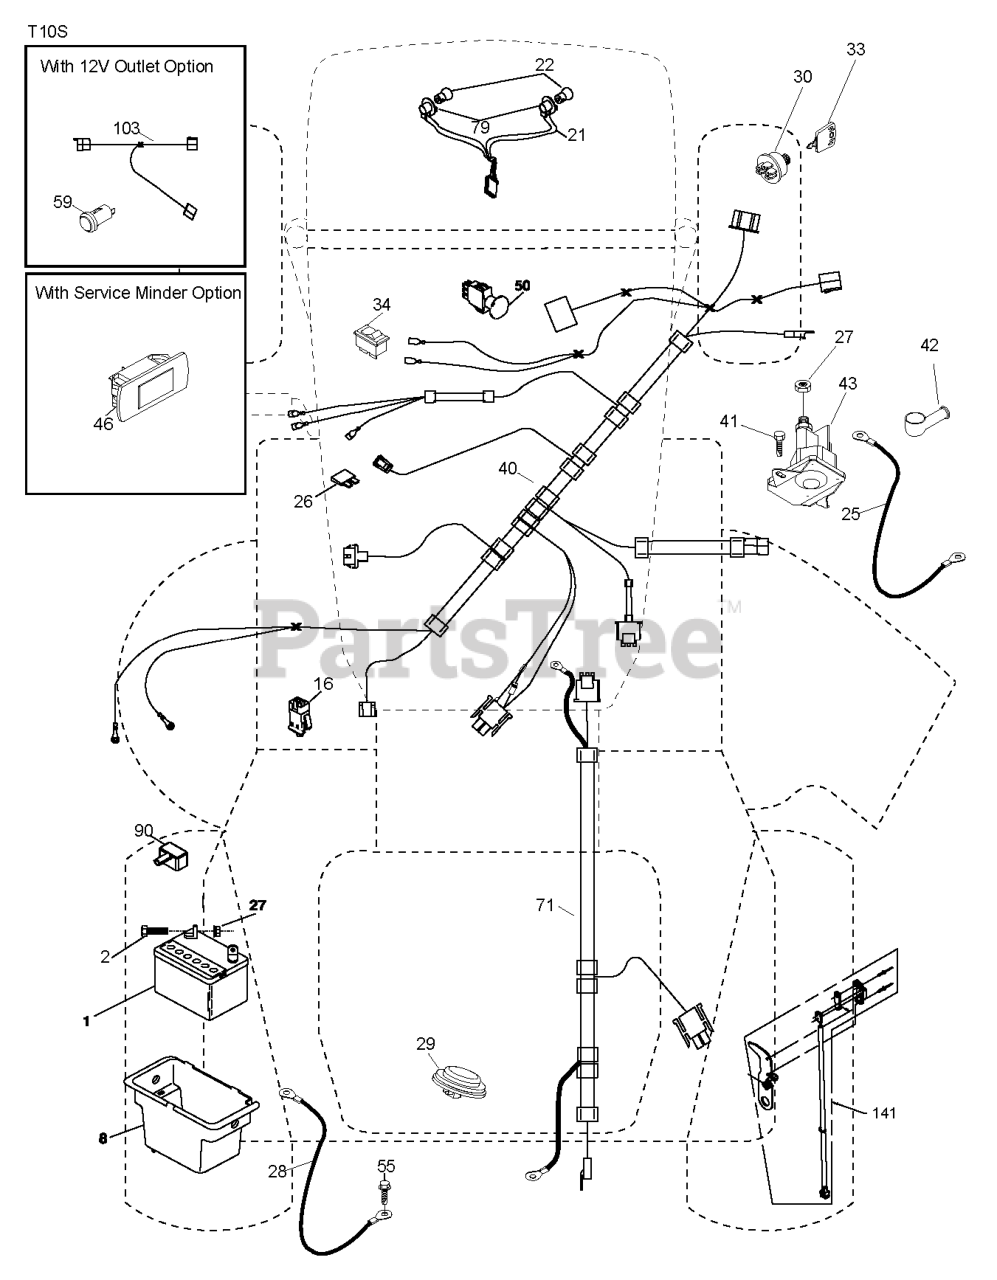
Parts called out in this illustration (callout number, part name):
1	REPL BY 532 12 38-99
2	BOLT.HEX.1/4.X.3/4.DICHROMATE
8	BOX.BATTERY.MNT.REAR.L
16	SWITCH INTERLOOK PUSH-IN
21	HARNESS.LIGHT W/4152J BULBS
25	CABLE.STARTER.6GA.BL/RED.14.
26	FUSE 20AMP
27	NUT
28	CABLE.BLACK.18"REAR.BA
29	SWITCH.SEAT.DELTA.OPC.
30	SWITCH.IGN.DELTA.W.LGH.ROS
33	KEY.CHAIN.BLISTER.PACK.GEN.INT
40	HARNESS.IGN.DASH.HUQ/P
41	SCREW
42	TERMINAL COVER
43	SOLENOID.W/BRASS.PLUNGER
46	RP.GUAGE.SRVCMNDR.HRMTR.
50	RP.PTO.SWITCH.8 TERMINAL.BLACK
55	SCREW 5/16"
71	HARNESS.IGN.CHASS.TEX.REAR.BAT
79	BULB HOLDER ASM.
90	COVER, TERMINAL BATTERY
141	KIT T2.ROS 71677
